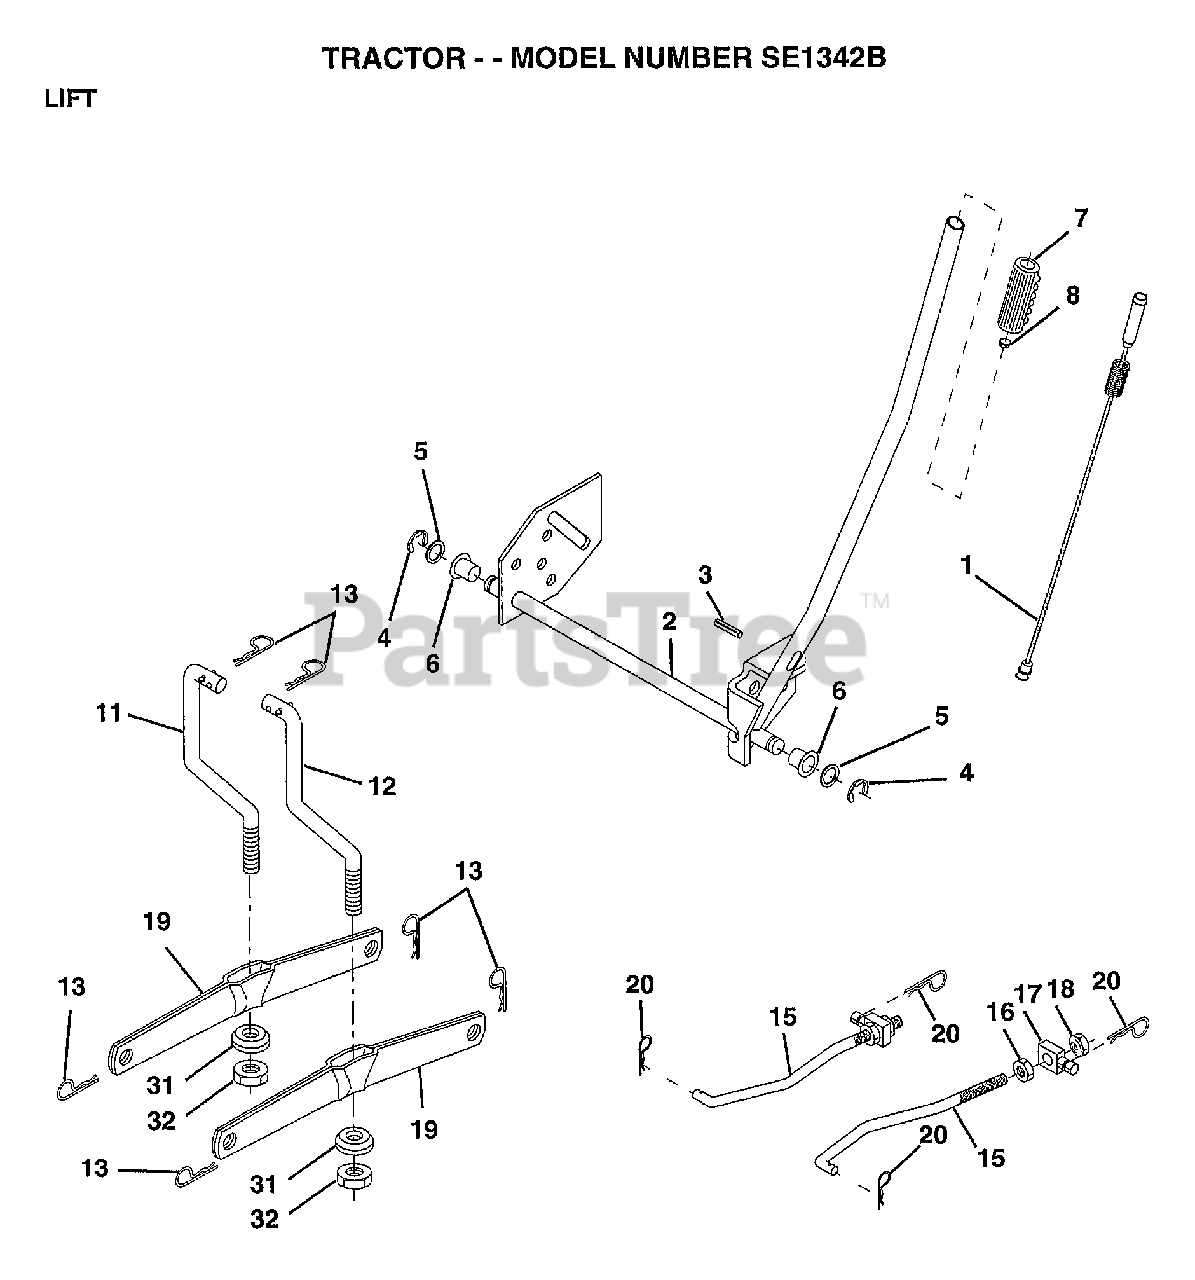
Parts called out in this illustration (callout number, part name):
1	WIRE ASM W.SPRING
2	"SHAFT ASM LIFT,RH"
3	PIN-GROOVE LT
5	WASHER
6	NYLON BEARING
7	GRIP
15	LINK.FRONT
16	NUT
17	TRUNION
18	NUT.LK.W/WSH.1/2.
19	ARM SUSP REAR
20	RETAINER.SPRING
31	BEARING PVT LH
32	NUT.CROWNLOCK.3/8
